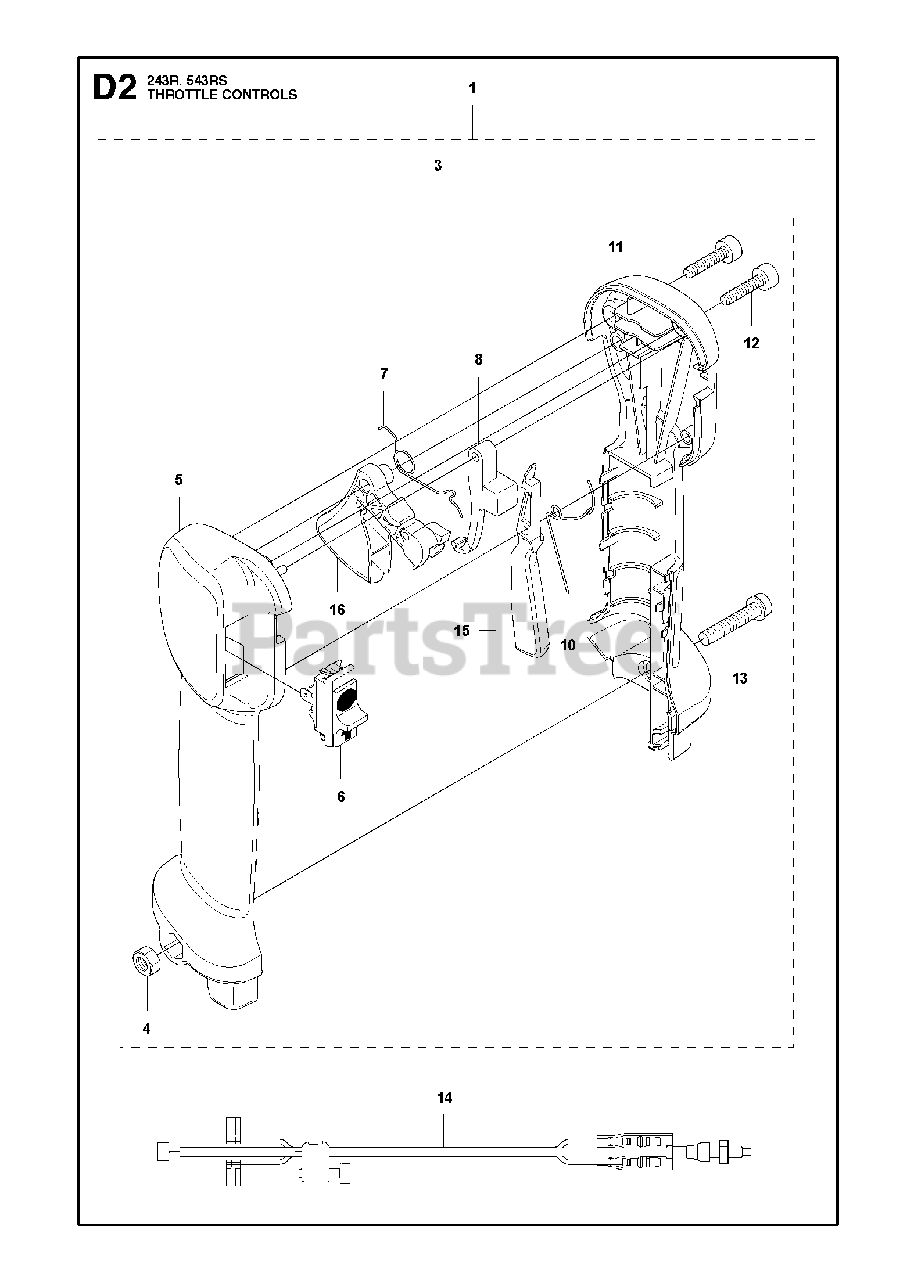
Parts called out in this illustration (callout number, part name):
1	THROTTLE CONTROL ASSY
3	HANDLE SYSTEM ASSY
4	NUT
5	HANDLE
6	START/STOP SWITCH
7	SPRING
8	STARTER THROTTLE LOCK
9	THROTTLE CONTROL
10	SPRING
11	HANDLE
12	SCREW IHSCT MT4X18 10.9 ZN/FE
13	SCREW IHSCFM
14	THROTTLE CABLE ASSY
15	THROTTLE LOCKOUT
16	THROTTLE CONTROL
